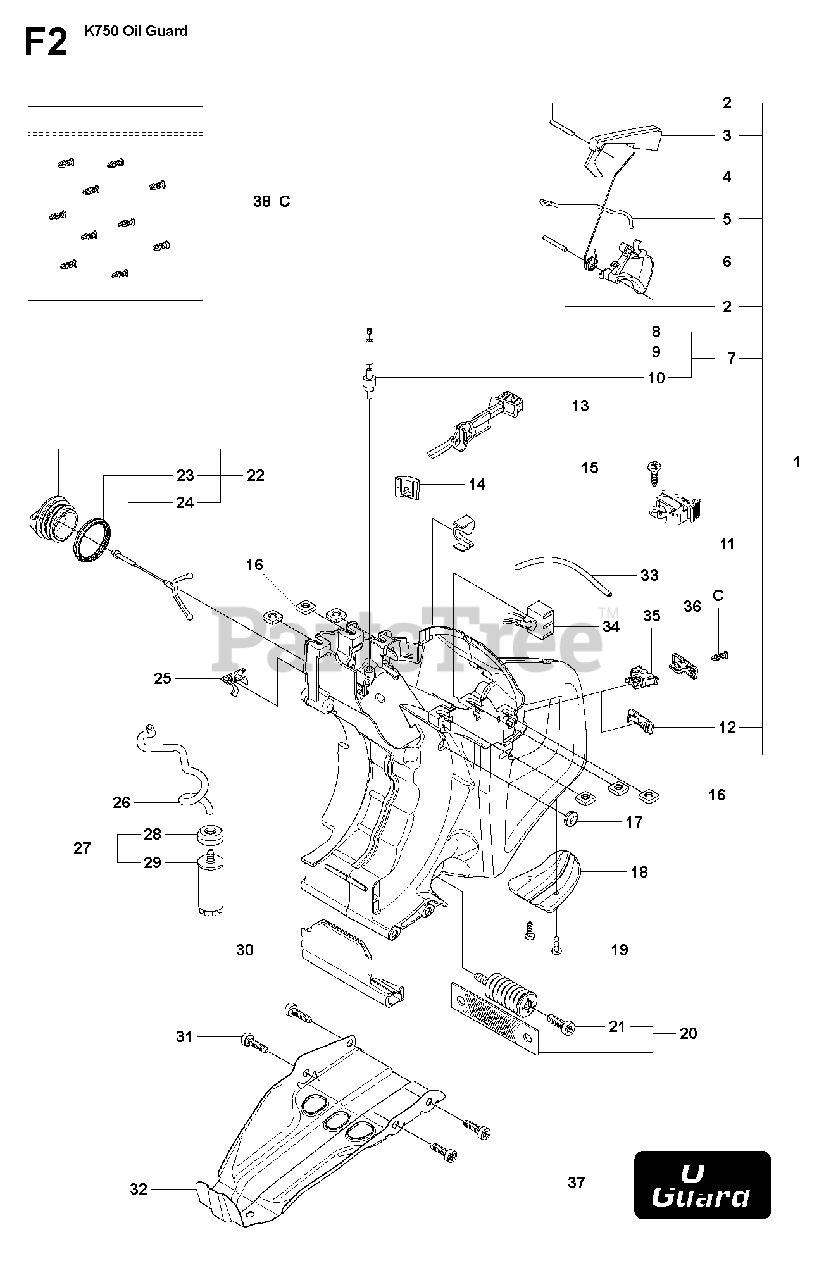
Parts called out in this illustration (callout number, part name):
1	FUEL TANKIncl. 2 - 7, 11, 12
2	PARALLEL PIN
3	THROTTLE LOCKOUT
4	SPRING
5	THROTTLE ROD
6	THROTTLE TRIGGER
7	TANK VENT ASSYIncl. 8 - 10
13	CHOKE CONTROL
15	SCREW CCRPANT
17	CABLE GROMMET
18	GROUND SUPPORT
19	SCREW CRCSFT
20	ANTIVIBRATION ELEMENTIncl. 21
21	SCREW ITXSCM
22	TANK CAP ASSYIncl. 23, 24
25	HUB CAP
26	FUEL HOSE
27	FUEL FILTERIncl. 28, 29
31	SCREW ITXSCT
33	FUEL HOSEOil Guard
34	ELECTRONIC BOXOil Guard
35	HOUSINGOil Guard
36	SWITCHOil Guard
37	LABELOil Guard
38	CUPOil Guard, Incl. 10 springs
